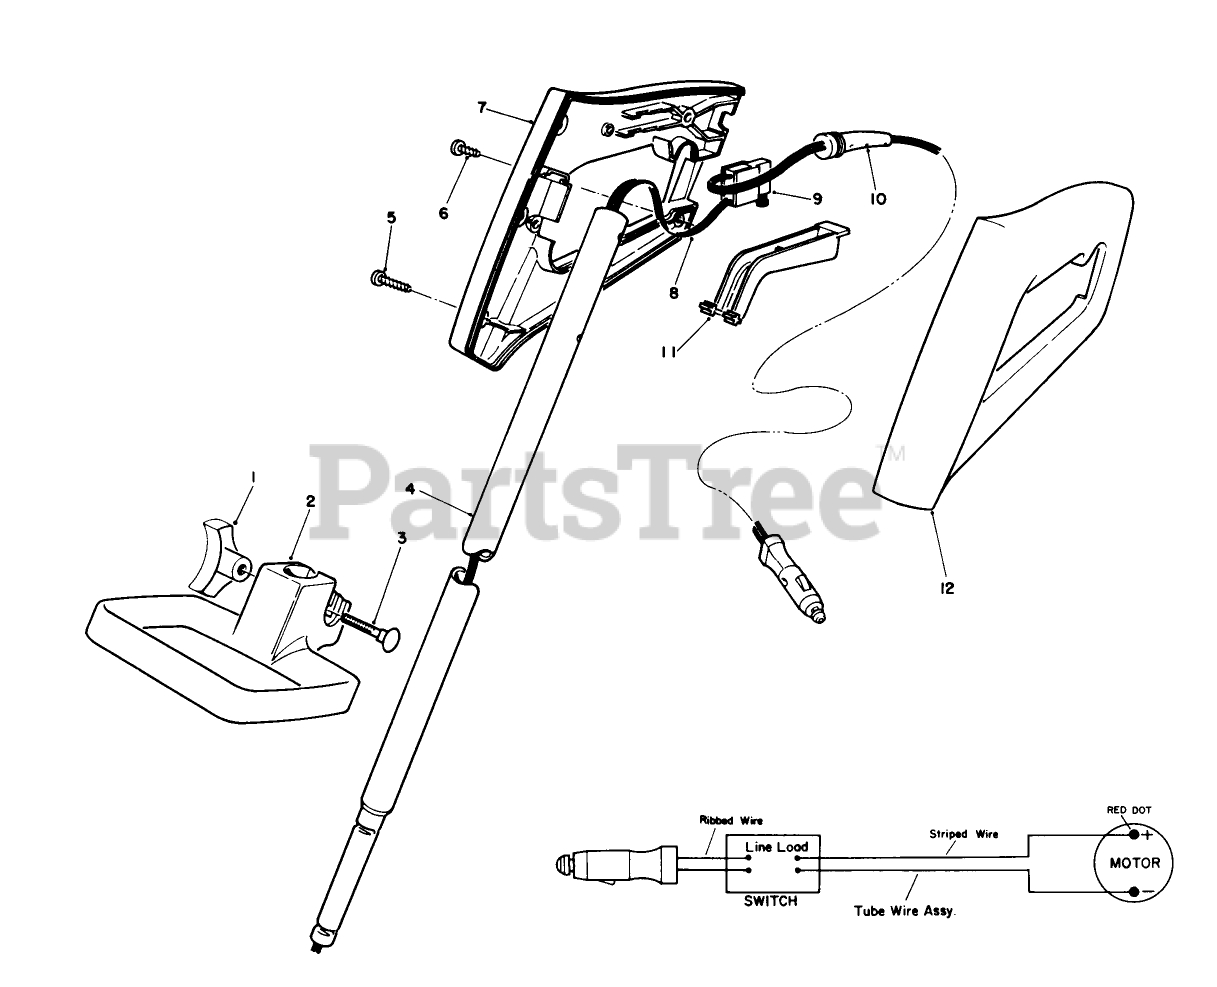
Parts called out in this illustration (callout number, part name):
1	HANDLE KNOB
2	Handle-Adjust
3	BOLT-CARR
4	TUBE-SINGLE
5	Screw
6	SCREW-PPH
7	HANDLE GRIP, RH
8	WIRE ASSEMBLY-TUBE
9	SWITCH
11	TRIMMER-SWITCH BAR
12	HANDLE GRIP, LH
